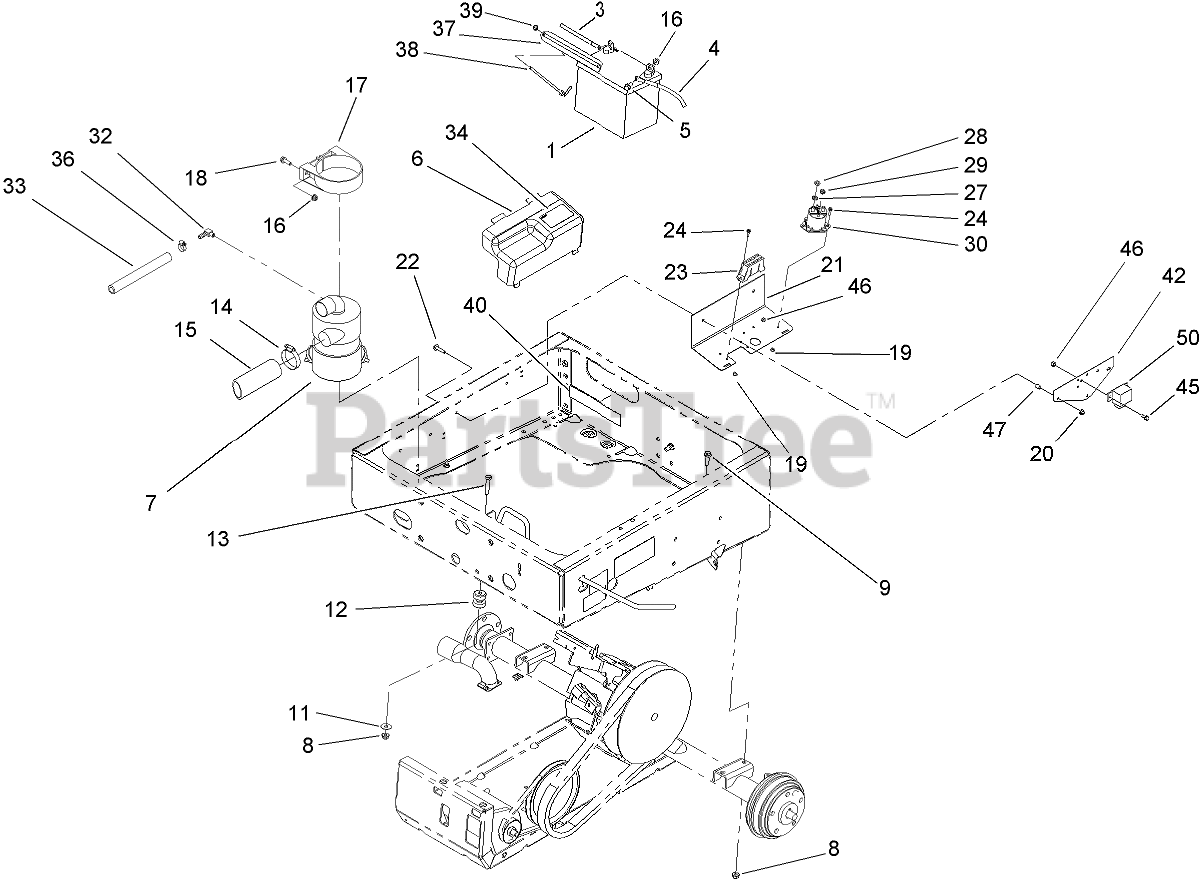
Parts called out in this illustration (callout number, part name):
1	BATTERY-DRY
3	CABLE-NEGATIVE
4	CABLE-POSITIVE
5	SCREW-HHF
6	COVER-ELECTRICAL
7	AIR CLEANER ASM
8	NUT-HF, NI
9	SCREW-HHF
11	WASHER-FLAT
12	MOUNT-ISO
13	SCREW-HH
14	CLAMP-HOSE
15	HOSE-INTAKE
16	NUT-HF, NI
17	BRACKET-MOUNTING
18	SCREW-HHF
19	NUT-LOCK, NI
20	NUT-HHF
21	MOUNT-COMPONENT
22	SCREW-HHF
23	HARNESS-WIRE, MAIN
24	SCREW-HWH
27	WASHER-LOCK
28	NUT-JAM
29	NUT-KEPS
30	SOLENOID
32	FITTING-90 DEG
33	HOSE-BREATHER
34	DECAL-INFORMATION
36	CLAMP-HOSE
37	CLAMP-BATTERY
38	HOOK-RETAIN, BATTERY
39	NUT-HF
40	Pad-Battery
42	BRACKET-IGNITION
45	SCREW-HHF
46	NUT-LOCK, NI
47	SPACER
50	RELAY
